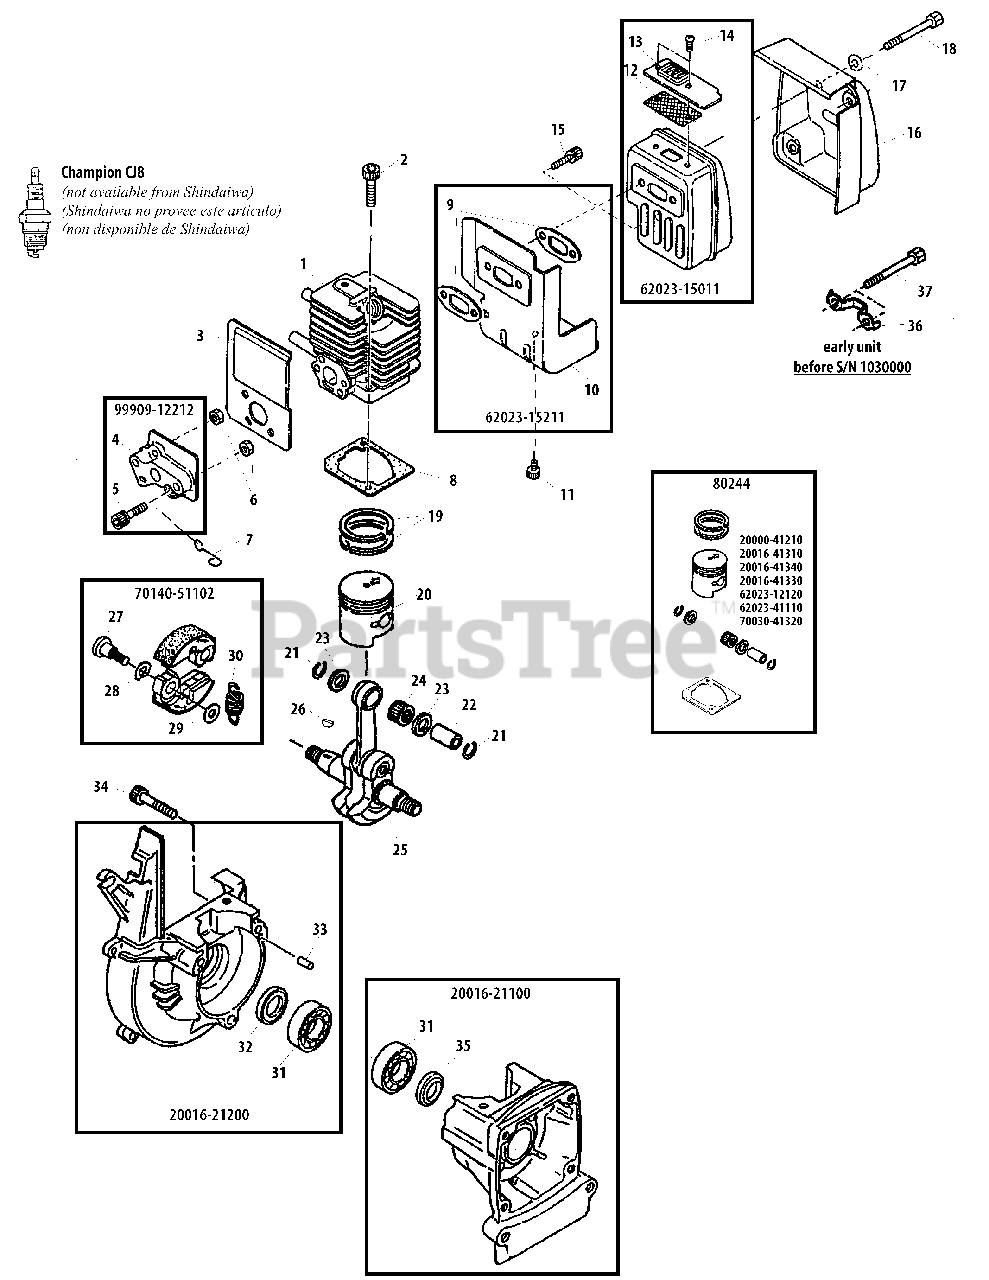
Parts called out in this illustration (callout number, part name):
1	CYLINDER
2	SCREW - 5X25
3	SHIELD, INTAKE
4	INSULATOR
5	SCREW - 5X30
6	NUT
7	HOLDER, VENT
8	GASKET, CYLINDER
9	SHIELD, EXHAUST
10	GASKET
11	SCREW - 5X8
12	SCREEN, SPARK ARRESTOR
13	TAIL PLATE
14	SCREW - 4X6
15	SCREW - 5X20
16	COVER, EXHAUST
17	WASHER - 5
18	SCREW - 5X60
19	RING, PISTON
20	PISTON
21	RING, RETAINING
22	PIN, PISTON
23	WASHER, THRUST
24	BEARING, NEEDLE
25	CRANKSHAFT ASSY
26	KEY - 3X10
27	BOLT, CLUTCH
28	WASHER - SPRING
29	WASHER - 6
30	SPRING, CLUTCH
31	BEARING, BALL - 6001C3
32	SEAL, OIL - 12
33	PIN - LOCATING
34	SCREW - 5X25
35	SEAL, OIL
36	PLATE, LOCK
20016-21100	CRANKCASE ASSY - REAR
20016-21200	CRANKCASE ASSY - FRONT
62023-15011	MUFFLER ASSY
70140-51102	CLUTCH ASSY
80244	PISTON ASSY
99909-12212	INSULATOR ASSY
